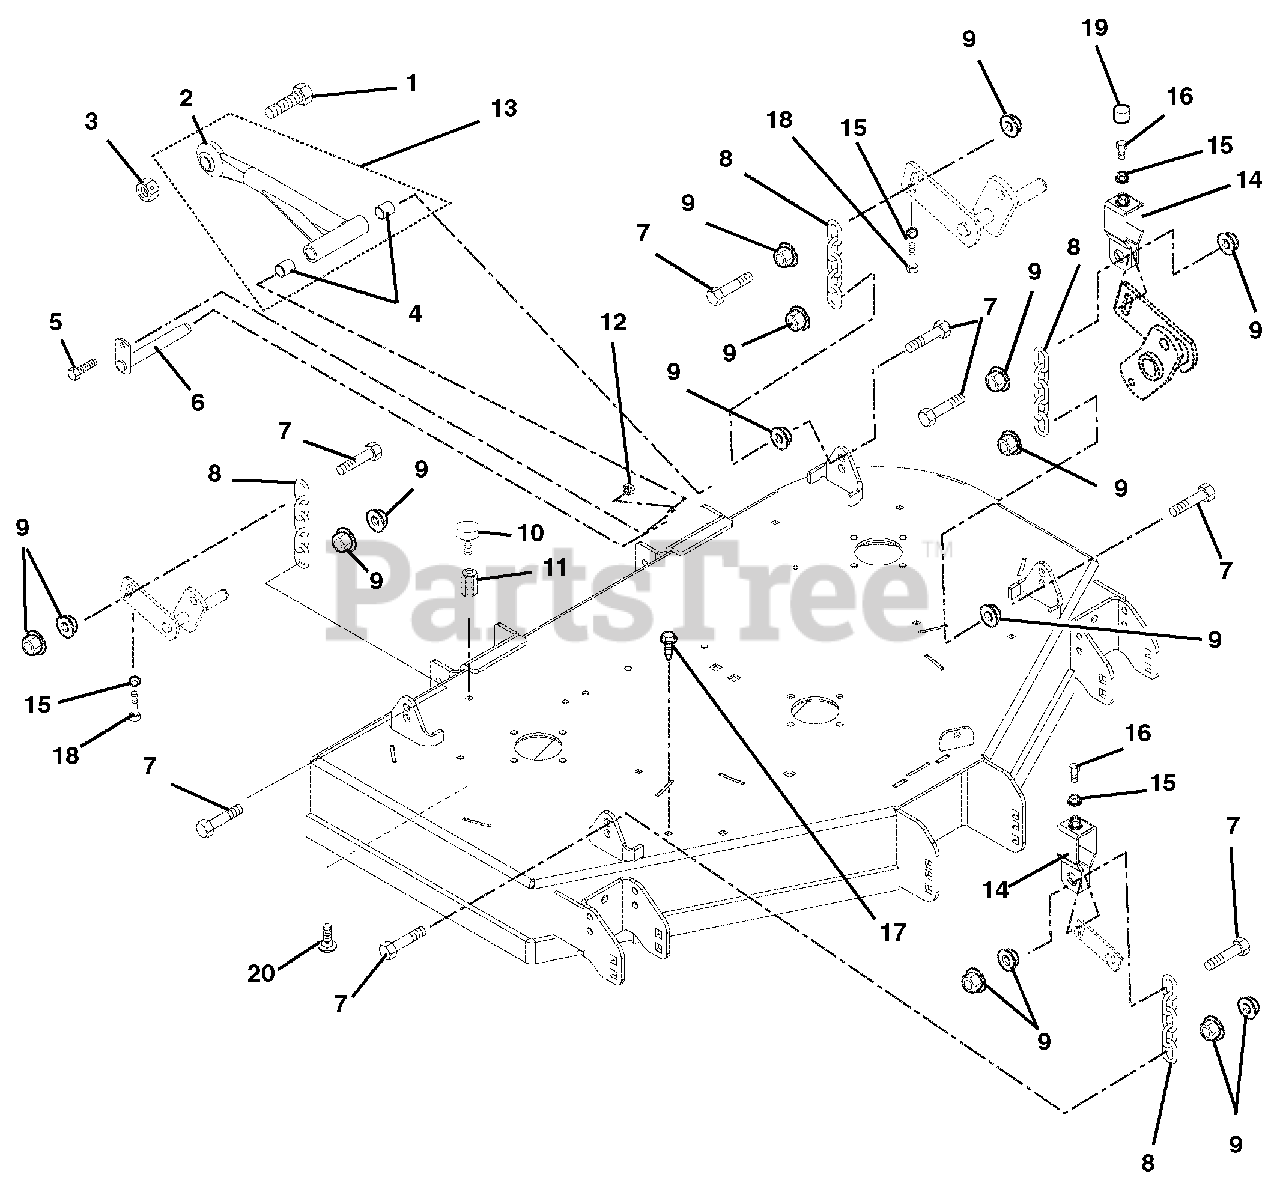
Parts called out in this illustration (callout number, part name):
1	Bolt, Hex .875-9 x 2.75 Grade 5
2	Mower Mounting Arm Weldment
3	Nut, Locking-Center .875-9
4	Bearing, .75 x .875 x 1.00
5	Bolt, Hex .38-16 x .75 Grade 5
6	Weldment, Mower Mounting Pin
7	Bolt, Hex M12-1.75 x 50 Grade 5
8	Chain, Link
9	Nut, Spin Lock-Flange M12-1.75
10	Bumper, Rubber
11	Nut, Coupling, .31-18 x 3.00
12	Nut, .38-16 Nyloc Flange
13	Assembly, Mower Mounting Arm (Includes item # 2 and item # 4)
14	Bracket, Deck Leveling
15	Nut-Jam .312-18
16	Bolt, Hex .31-18 x 2.00 Full Thread
17	Screw, Tapping .38-16 x .50 Hex Washer Head Thread
18	Bolt, Hex .312-18 x 1.50 Grade 5
19	Cap, Vinyl .50 ID x 1.50LG x .055
20	Bolt, Round Head Square Neck, .31-18 x .75 Loc-Tite®
